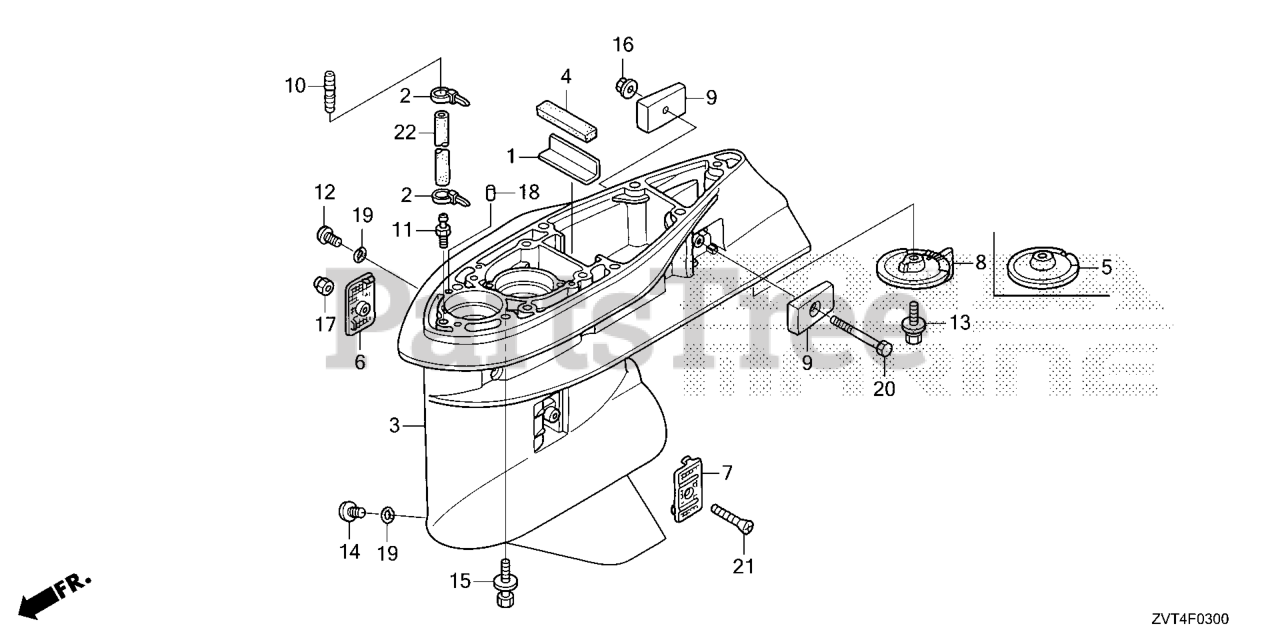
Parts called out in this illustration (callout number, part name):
1	PLATE, RUBBER SETTING
2	BAND, WIRE
3	CASE, GEAR *NHB14M* (AQUA MARINE SILVER METALLIC)
3	CASE,GEAR*NH565*
4	GROMMET, GEAR CASE
6	SCREEN, R. WATER
7	SCREEN, L. WATER
8	TAB, TRIM *NHB14M* (AQUA MARINE SILVER METALLIC)
8	TAB, TRIM *NH565* (GRAND PRIX WHITE)
9	METAL, ANODE
10	END, NIPPLE
11	NIPPLE, SENSOR
12	BOLT, OIL CHECK
13	BOLT-WASHER (10X32)
14	BOLT, DRAIN PLUG
15	BOLT-WASHER (10X40)
16	NUT, SELF-LOCK (6MM)
17	NUT, SELF-LOCK (5MM)
18	PIN, DOWEL (6X10)
19	O-RING (6.9X1.45)
20	BOLT, HEX. (6X50)
21	SCREW, OVAL (5X50)
22	BULK HOSE, VACUUM (5X3000) (5X250)
